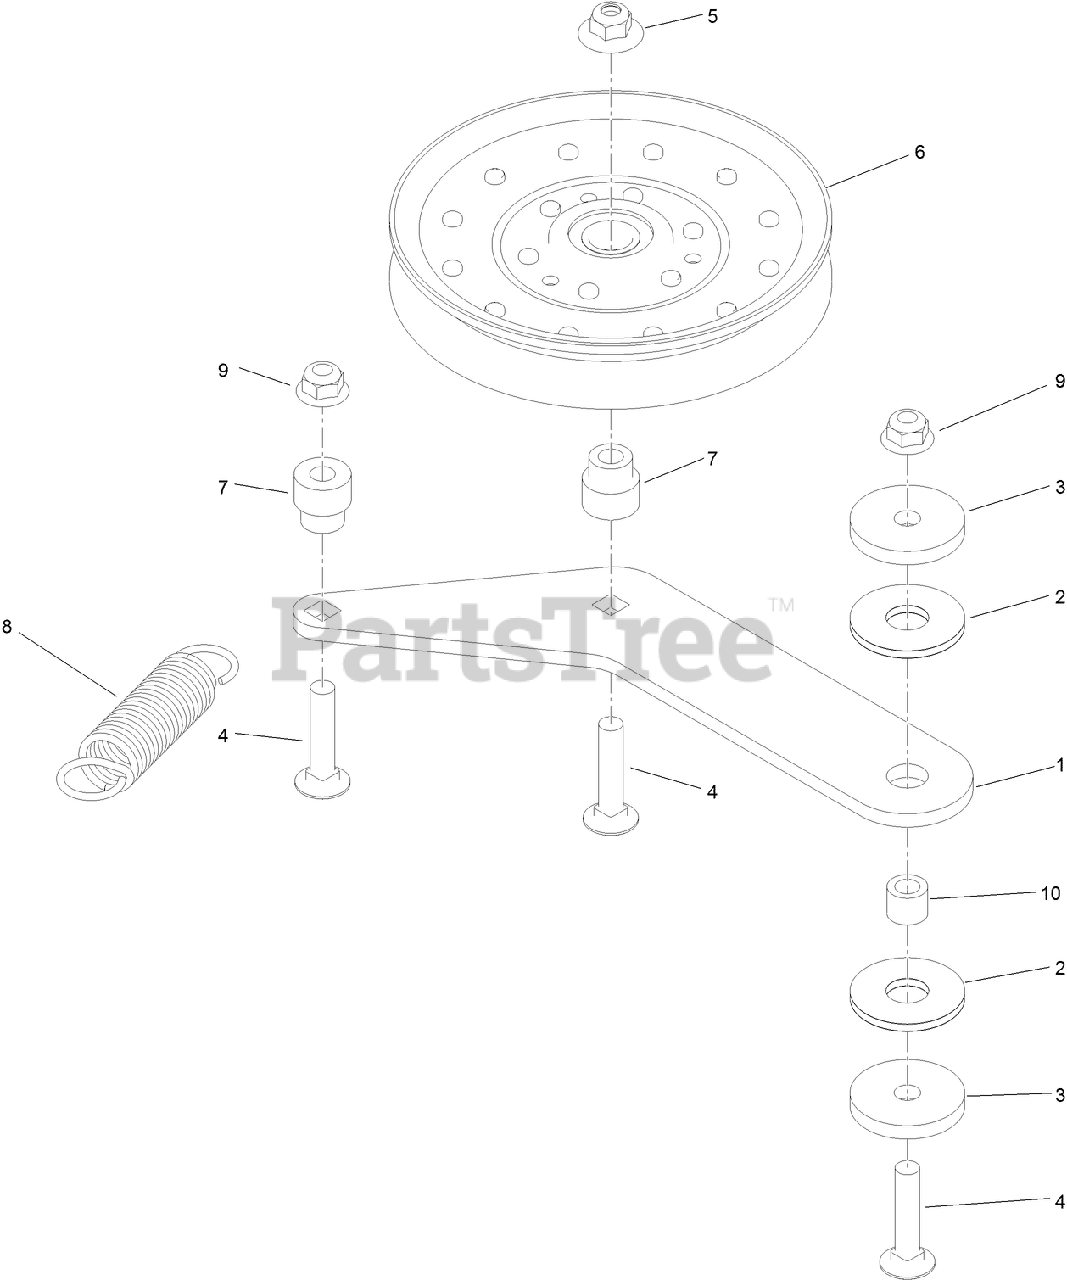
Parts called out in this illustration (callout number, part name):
1	ARM-IDLER, RH
2	WASHER-FRICTION, COMPOSITE
3	WASHER-PLAIN
4	SCREW-CARR
5	NUT-FLANGE, NI
6	IDLER-PULLEY, FLAT
7	BUSHING-IDLER
8	SPRING-EXTENSION
9	NUT-HF, NI
10	BUSHING-LEVER, LIFT
